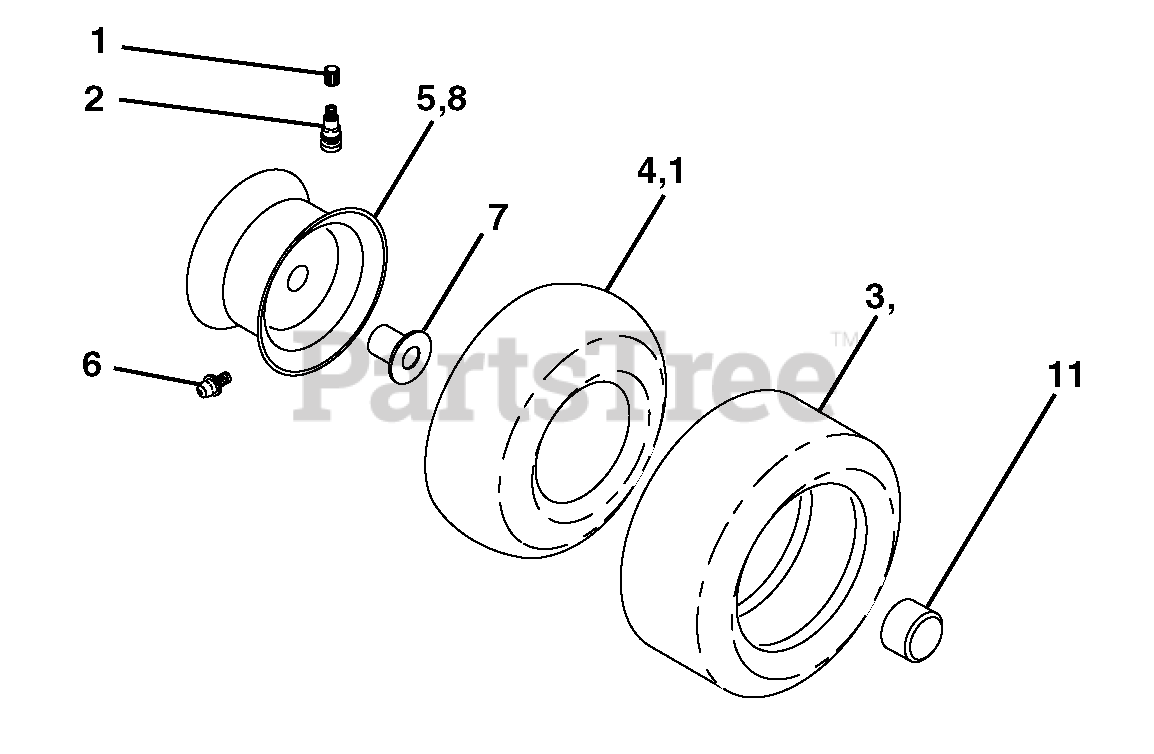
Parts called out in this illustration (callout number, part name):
1	Cap Valve Tire
2	Stem Valve
3	Tire F T 15 x 6 0 - 6 Service
4	Tube Front
5	Rim Asm 6" front Service
6	Fitting Grease
7	Bearing Flange
8	Rim Asm 8" rear Service
9	Tire R T 18 x 9.5-8 Service
10	Tube Rear
11	Cap Axle Blk 1 50 x 1 00
11	Sealant, Tire ( 10 oz. Tube)
